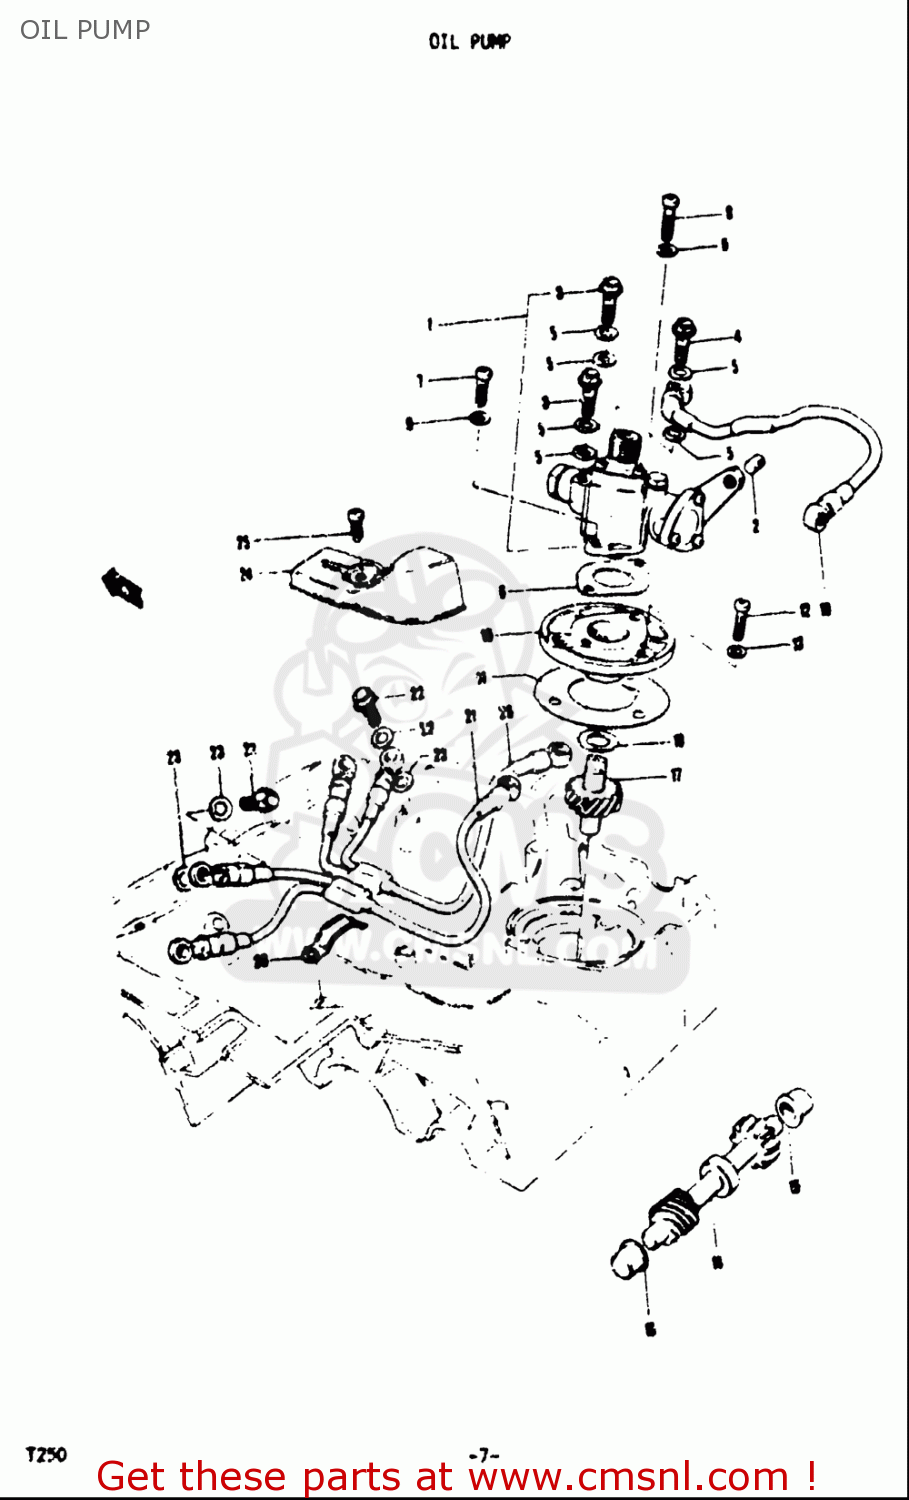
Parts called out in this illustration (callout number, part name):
2	TERMINAL, CABLE
3	UNION
5	GASKET(6.2X11X1).2 (NAS)
7	SCREW
9	WASHER
11	GASKET,OIL PUMP GEAR CASE (MCA)
13	WASHER
18	SHIM(10X20X1)
22	UNION BOLT
23	GASKET(6.2X11X1).2 (NAS)
